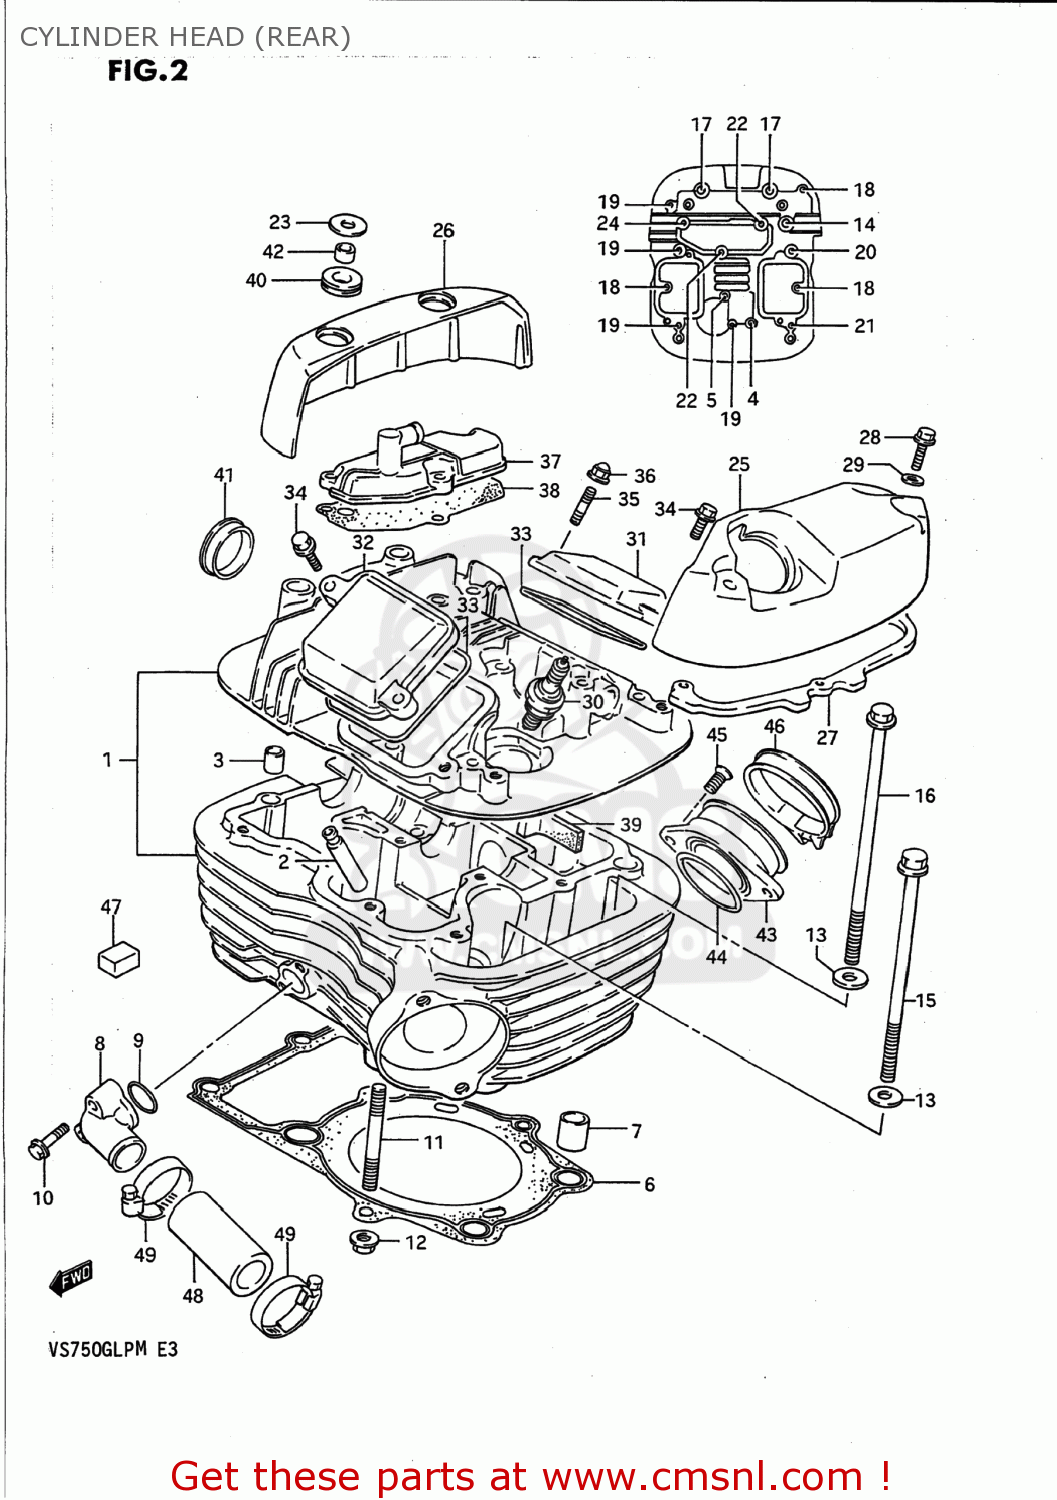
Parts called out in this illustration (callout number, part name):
1	HEAD ASSEMBLY,CYLINDER,REAR
2	GUIDE,VALVE
3	PIN(11X14)
4	BOLT(6X50)
5	BOLT(6X55)
6	GASKET,CYLINDER HEAD RR (MCA)
7	PIN
8	UNION,CYLINDER HEAD WATER
9	O RING(D:2.4,ID:17.8)
10	BOLT
11	BOLT,STUD
12	NUT
13	WASHER(10.5X22X2.3)
14	BOLT(8X140)
15	BOLT(10X155)
16	BOLT(10X165)
17	BOLT(8X245)
18	BOLT 6X25
19	BOLT
20	BOLT
21	BOLT
22	BOLT(6X55)
23	WASHER (8.2X24X1.6)
24	BOLT 6X20
25	CAP,CYLINDER HEAD COVER RR,L
26	CAP,CYLINDER HEAD COVER RR,R
27	CUSHION,RR,L CAP
28	BOLT
29	WASHER
30	SPARK PLUG DP8EA-9
31	CAP,INSPECTION
32	CAP,INSPECTION,EXHAUST
33	GASKET,INSPECTION CAP (NAS)
34	BOLT
35	STUD 6X16
36	NUT
37	COVER,BREATHER
38	GASKET,BREATHER COVER (NAS)
39	PLATE,HEAD COVER RR
40	CUSHION
41	PLUG
42	BUSH
43	PIPE,INTAKE
44	O-RING (D:2.4 ID:39.7)
45	SCREW
46	CLAMP,PIPE
47	PAD
48	HOSE,CYLINDER HEAD JOINT
49	CLAMP
